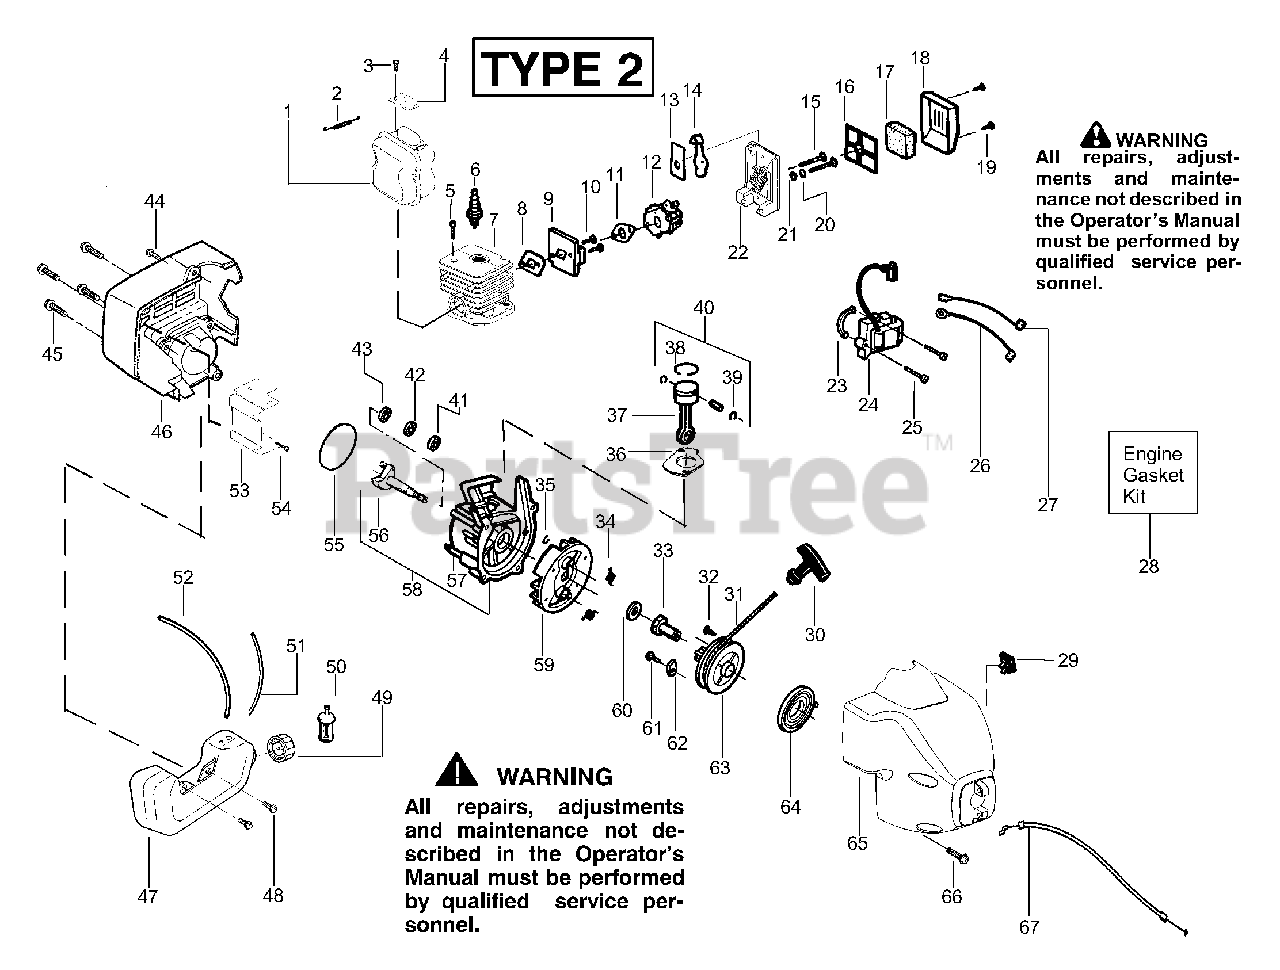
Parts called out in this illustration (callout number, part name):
1	Kit-Muffler
2	Muffler Spring
4	Screen-Spark Arrestor
5	Screw-Cylinder
6	Spark Plug (RCJ-6Y)
7	Kit-Cylinder
8	Gasket-Cylinder/Carb.
9	Carb. Adapter
10	Screw-Carb Adptr.
11	Gasket-Carb.
12	Kit-Carb. Ass'y. (C1U-W10)
12	Kit-Carb. Ass'y. (C1U-W10B)
13	Choke Plate
14	Choke Shutter
15	Screw-Carburetor
16	Filter Support Plate
17	Air FIlter Foam
18	Air Filter Cover
19	Screw-Air Box
20	Choke Spacer
23	Spacer-Ignit. Module
24	Ignition Module
25	Screw-Ignit. Module
26	Ground Wire Ass'y.
27	Lead Wire Ass'y.
28	Kit-Engine Gasket
29	Switch-Momentary
30	Starter Handle
31	Kit-Rope
33	Drive Coupling
34	Spring Starter Dog
35	Ret. Ring-C'case
36	Gasket-Cylinder
37	Connecting Rod Assy.
38	Piston Ring
39	Piston Pin Retainer
40	Kit-Piston
41	Outer Bearing
42	C'case Seal
43	Inner Bearing
44	Screw-Shd/Fan Hsg
45	Screw
46	Rear Shroud
47	Fuel Tank Ass'y.
48	Retainer
49	Fuel Cap Assy.
50	Fuel Pickup Assy
51	Fuel Line (Small)
52	Fuel Line (Large)
53	Shield-Heat
54	Screw-Heat Shield
55	O-ring-C'case
56	Crankshaft Ass'y.
57	Crankcase Assy.
58	C'case/C'shaft Assy.
59	Flywheel Ass'y.
60	Washer-Flat
61	Screw-Pulley
62	Retainer-Pulley
63	Kit-Starter Pulley
64	Starter Spring
65	Assy.-Fan Hsg.
66	Screw
67	Assy-Throttle Cable
